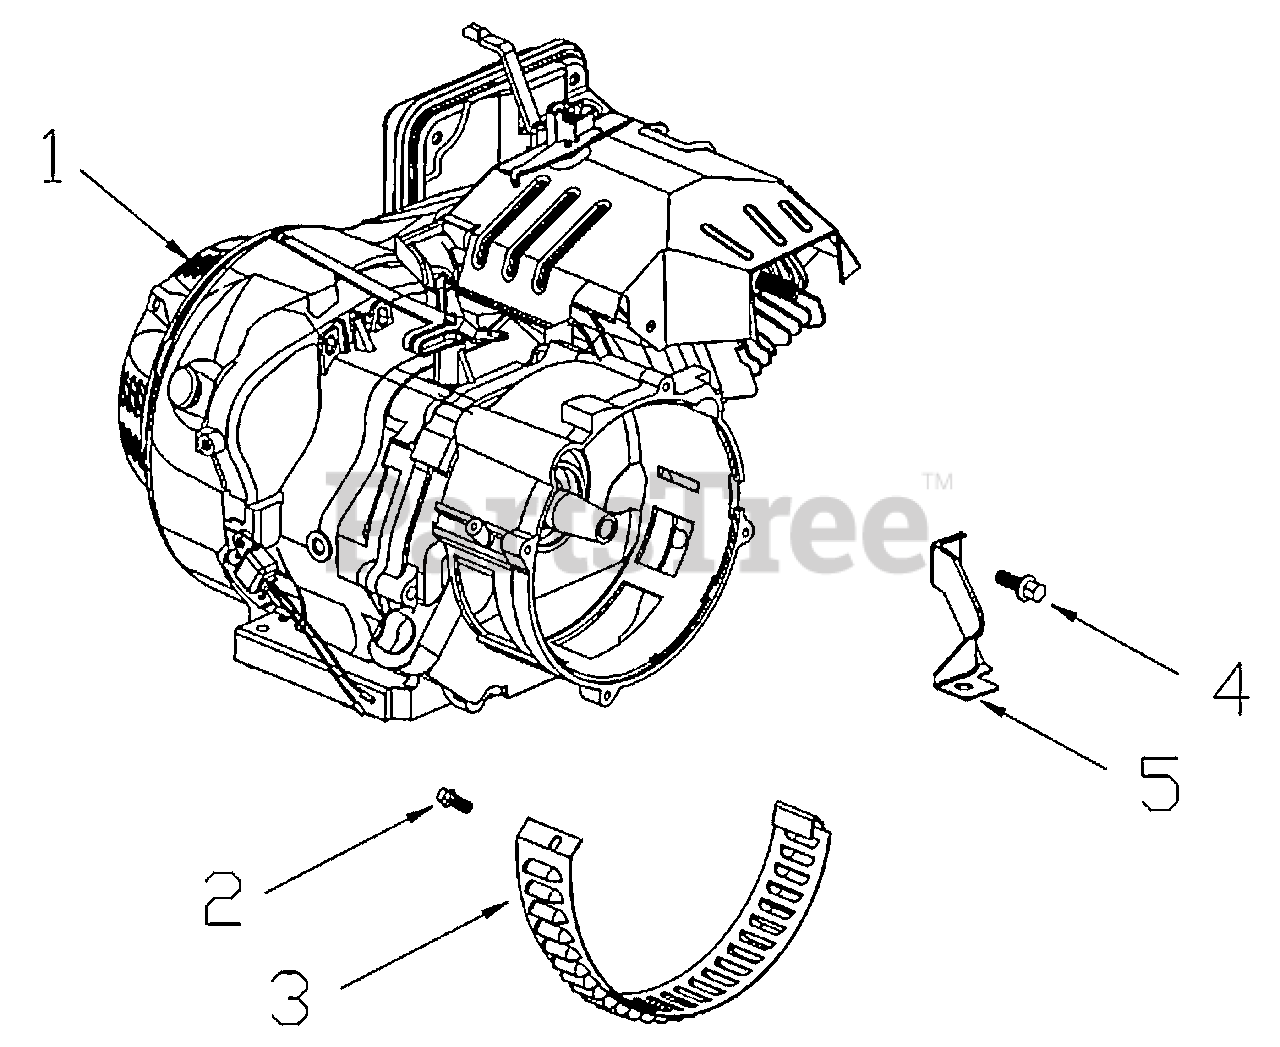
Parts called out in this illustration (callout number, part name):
1	ENGINE G390FA
2	BOLT, FLANGE M5x10
3	COVER, DUST
4	BOLT, FLANGE M6x12
5	BRACKET, AIR CLEANER
